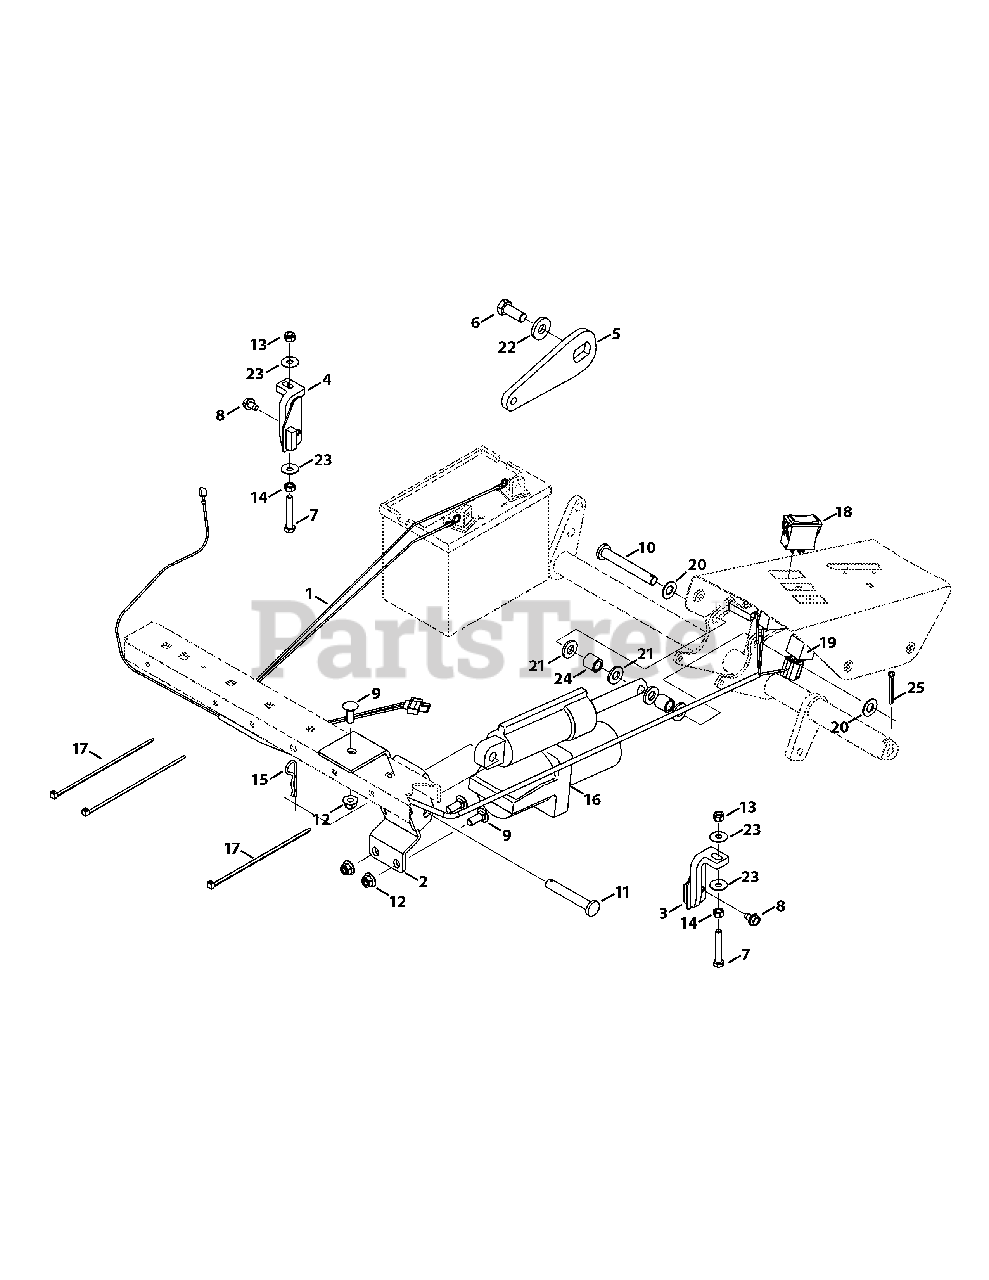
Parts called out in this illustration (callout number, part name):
1	Deck Lift Harness
2	Deck Lift Cylinder Mount
6	Hex Screw, 1/2- x 1.25
7	Hex Screw, 5/16-24 x 2.00
8	Hex Wshr. Screw, 5/16-18 x .500
9	Carriage Bolt, 3/8-16 x 1.00
10	Clevis Pin, .500 x 3.75
11	Clevis Pin, .500 x 3.2
12	Flange Lock Nut, 3/8-16
13	Hex Lock Nut, 5/16-24
14	Hex Nut, 5/16-24
15	Cotter Pin, .125 x 2.5
16	Lift Cylinder
17	Cable Tie, 3/16 x .05 x 7.4
18	Deck Lift Switch
19	SPDT Relay
20	Flat Washer, .510 x 1.000 x .060
21	Flt. Washer, .510 x 1.000 x .125
22	Flt. Washer, .531 x 1.25 x .181
23	Washer, .325 x .930 x .045
24	Spacer, .501 x .750 x .775
25	Cotter Pin, 1/8 x 1.00
